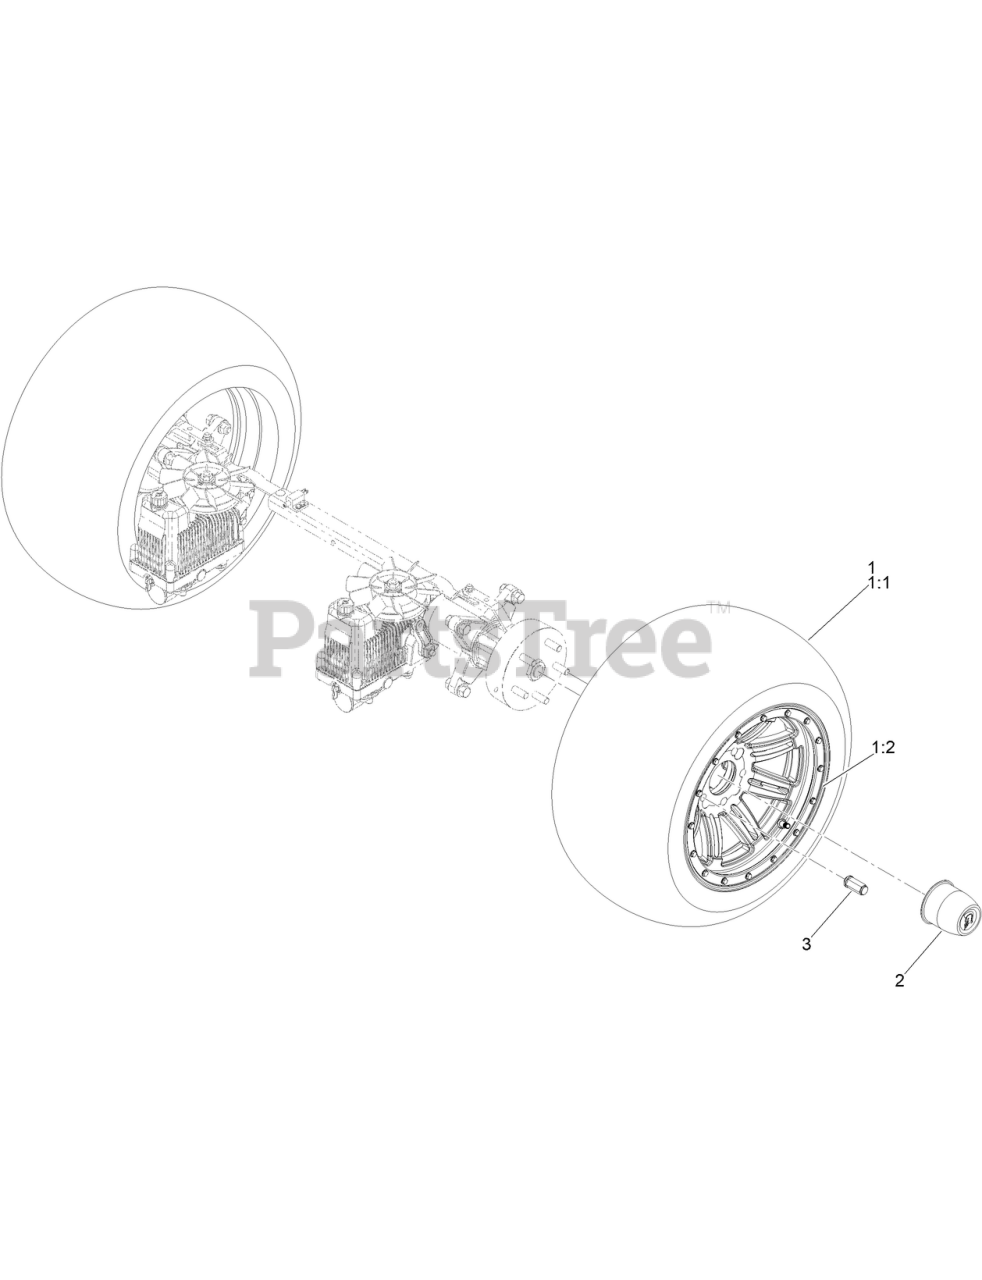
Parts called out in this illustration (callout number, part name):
1	RT/SRT 61/72IN DECK RR WHL ASSM 24X12-12
1:1	24X 12 X 12 SOFT RIDE RADIAL TIRE ONLY
1:2	8IN STEEL WHEEL
2	RR STEEL WHEEL SILVER CNTR CAP
3	LUG NUTS
